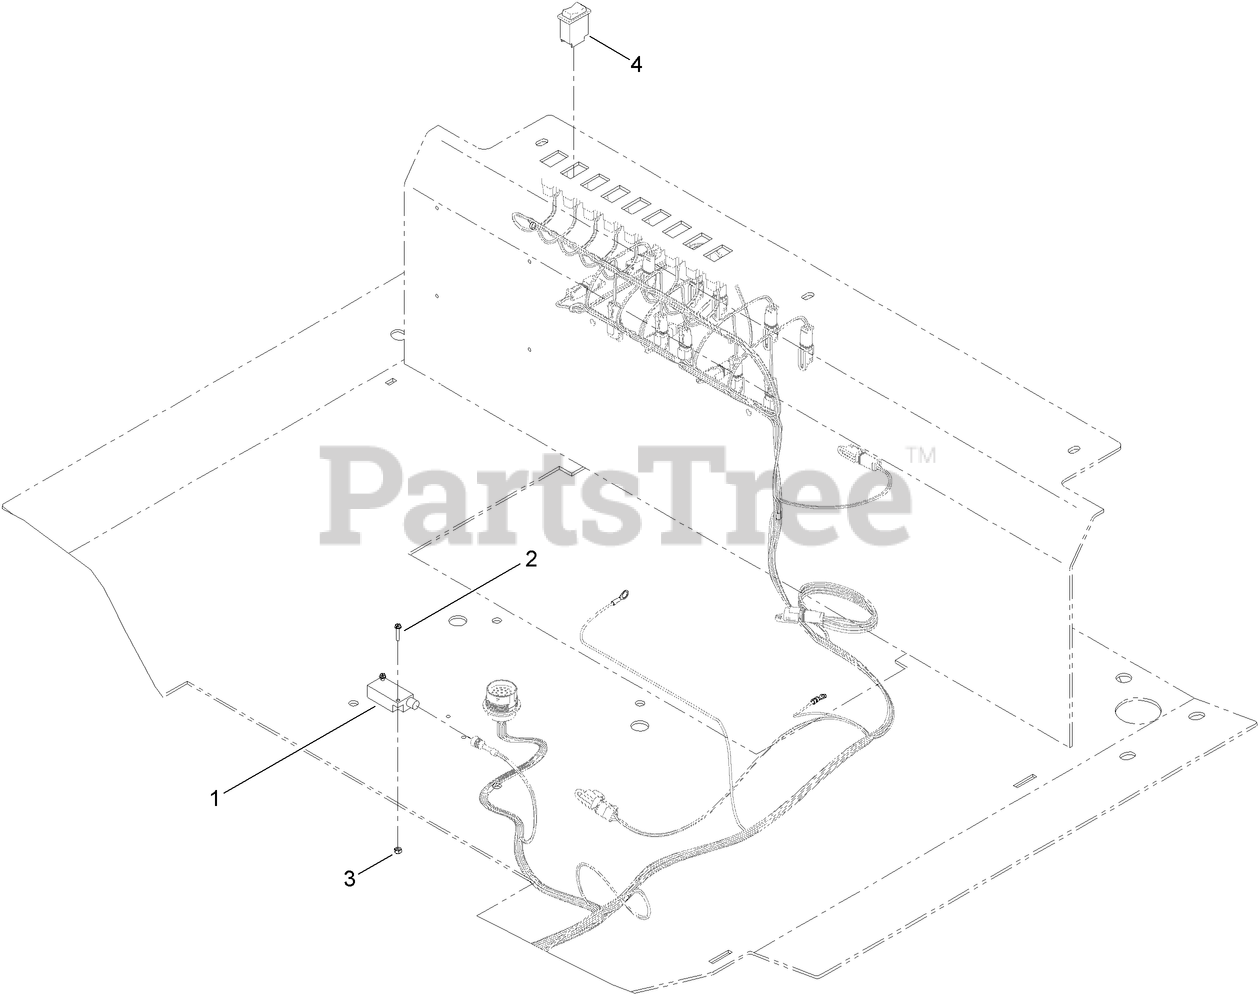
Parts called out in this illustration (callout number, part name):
1	SENSOR-TILT WITH FILTERING
2	SCREW-SHWH
3	NUT-LOCK
4	SWITCH-ROCKER, 2 POLE (ON/OFF)
